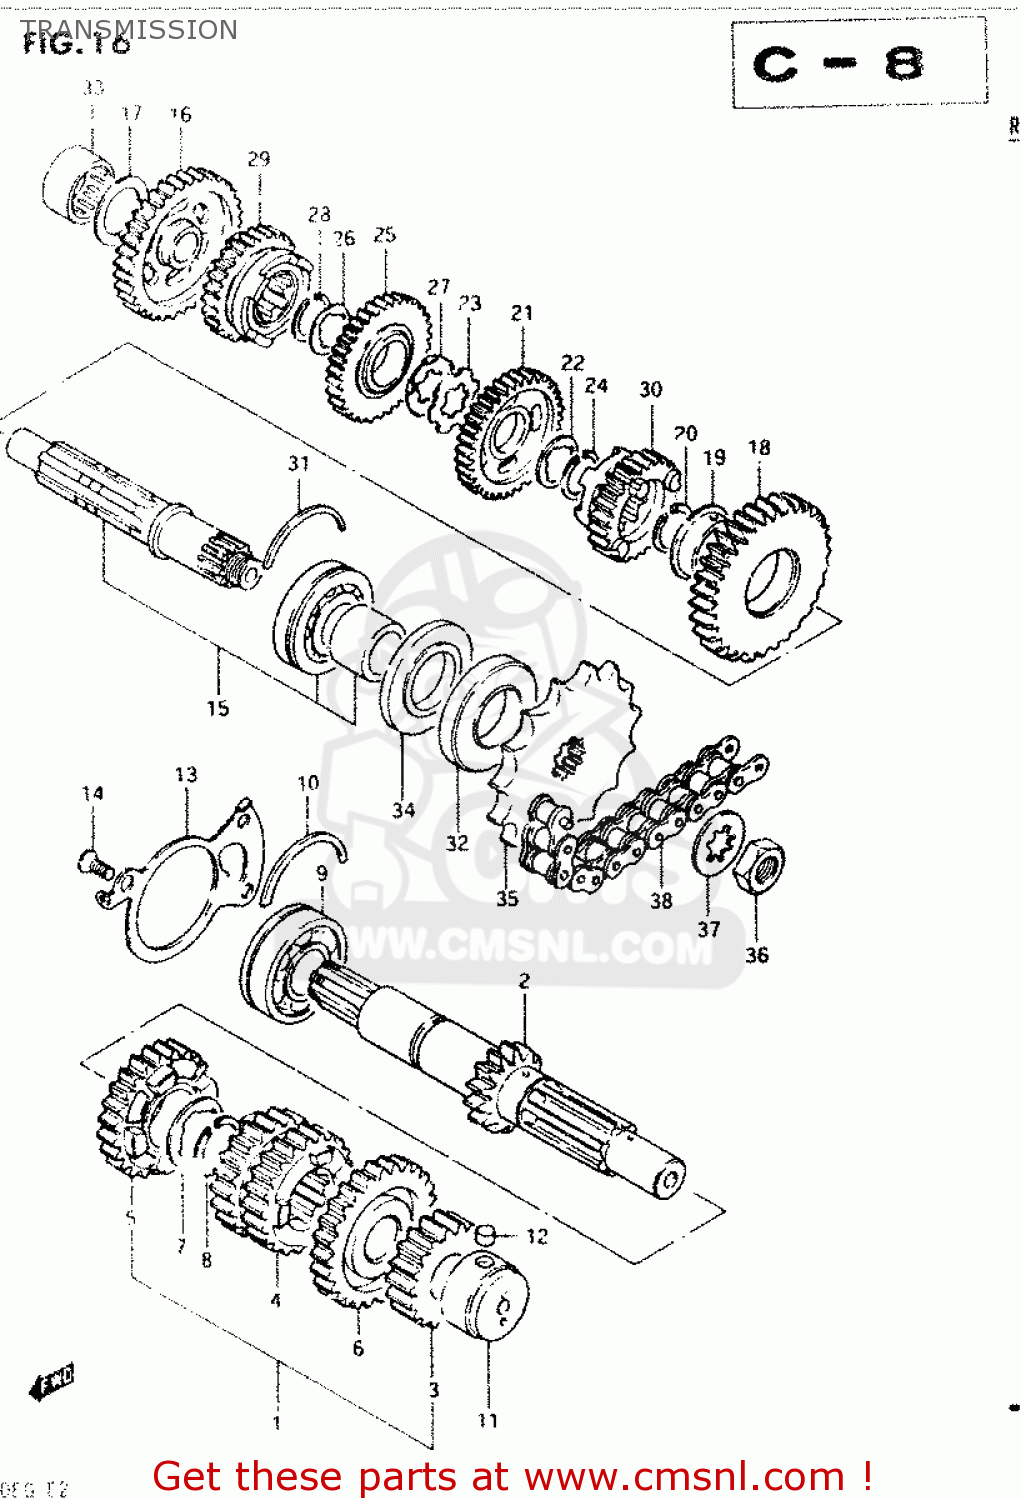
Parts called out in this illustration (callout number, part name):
1	SHAFT,COUNTER
2	SHAFT,COUNTER
3	GEAR,2ND DRIVE(NT:18)
4	GEAR,THIRD DRIVE
5	GEAR,FIFTH DRIVE
6	GEAR,SIXTH DRIVE
7	WASHER
8	CIRCLIP
9	BEARING(25X62X17)
10	C-RING
11	ROLLER BEARING (20X34X2
12	PIN
13	PLATE,COUNTERSHAFT BEARING
14	SCREW
15	SHAFT,DRIVE
16	GEAR,FIRST DRIVEN
17	WASHER
18	GEAR,SECOND DRIVEN
19	BUSHING
20	CIRCLIP
21	GEAR,THIRD DRIVEN
22	WASHER,LOCK
23	WASHER,LOCK
24	CIRCLIP
25	GEAR,FOURTH DRIVEN
26	WASHER,LOCK
27	WASHER
28	CIRCLIP
29	GEAR,5TH DRIVEN(NT:25)
30	GEAR,SIXTH DRIVEN
31	C-RING
32	SEAL,OIL(32X62X7)
33	ROLLER BEARING (20X34X1
34	SEAL,OIL(32X62X5.5)
35	SPROCKET,ENGINE(NT:16)
36	NUT
37	WASHER
38	CHAIN ASSEMBLY,DRIVE
